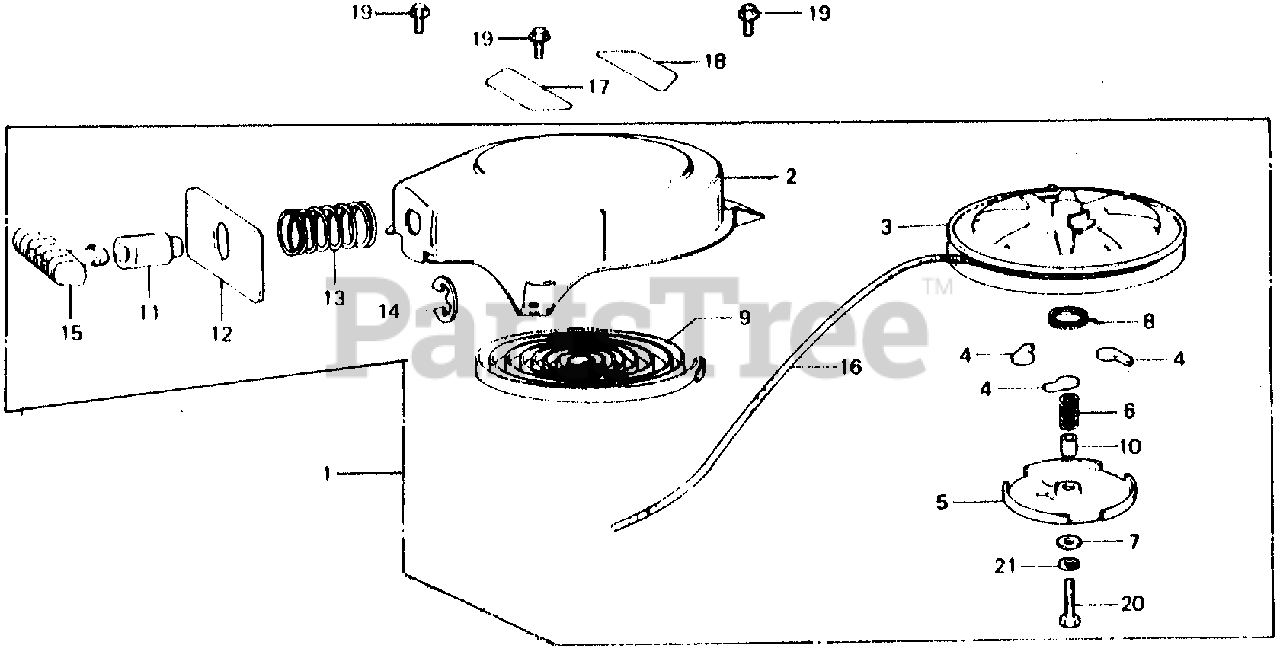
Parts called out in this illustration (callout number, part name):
1	STARTER ASSY., RECOIL
2	CASE, RECOIL STARTER
3	PULLEY, RECOIL STARTER
4	RATCHET, STARTER
5	PLATE, FRICTION
6	SPRING, FRICTION
8	SPRING, SETTING
9	SPRING, RECOIL STARTER
11	GUIDE, ROPE
12	PLATE, SEAL
13	SPRING, SEAL PLATE
15	GRIP, STARTER
16	ROPE, RECOIL STARTER (NA USE ALT:08540-ZG921-11)
17	MARK, RECOIL STARTER CAUTION
18	MARK, RECOIL STARTER CAUTION
19	BOLT, FLANGE (6X12)
20	BOLT, HEX. (6X25)
21	WASHER, SPRING (6MM)
